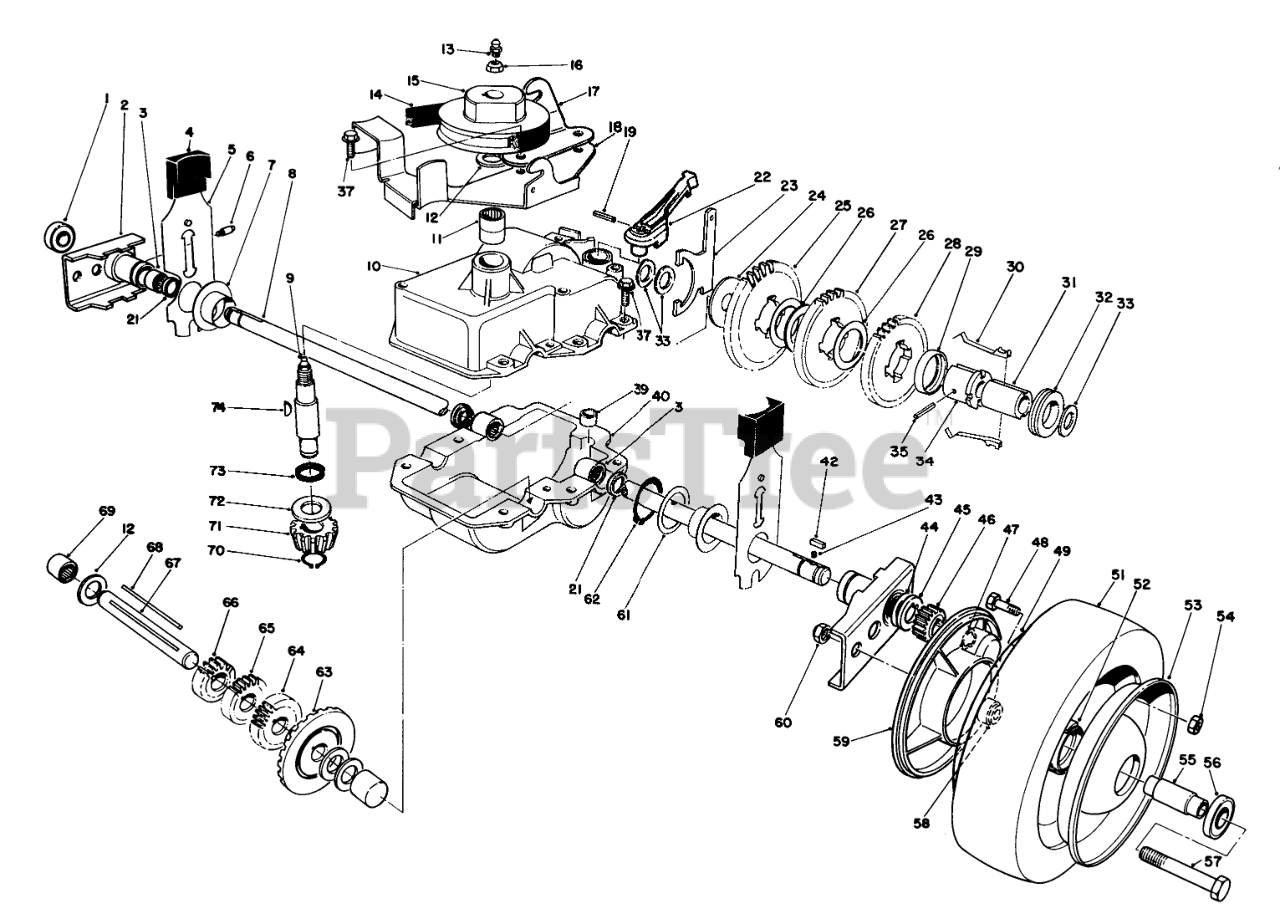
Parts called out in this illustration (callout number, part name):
1	BEARING-WHEEL
2	Pivot Arm Assembly (Incl. Ref. #1, 3, 6 & 21)
3	BEARING-ROLLER
4	KNOB-ARM
5	REAR SPRING ARM ASM
6	FITTING-GREASE
7	CAP-END
8	SHAFT-OUTPUT
9	Shaft-Input (Incl Ref. #13)
10	Upper Case Assembly (Incl. Ref. #11 & 73)
11	BEARING-NEEDLE
12	WASHER-THRUST
13	FITTING-GREASE, ZERK
14	V-BELT
15	PULLEY
16	NUT-HEX
17	Bracket-Traction Engage
18	Belt Guide Bracket
19	PIN-COIL
21	SEAL-OIL
22	LEVER-SHIFT
23	YOKE-SHIFT
24	WASHER
26	WASHER
27	GEAR-42T
28	GEAR-38T
29	RETAINER-KEY
30	KEY-SHIFT
31	SLEEVE
32	COLLAR-SHIFT
33	WASHER-PLAIN
34	SLEEVE-GEAR
35	PIN-GROOVE
37	SCREW-HWHTF
39	BUSHING-YOKE
40	CASE-GEAR, LOWER
42	KEY RECTANGULAR
43	SPRING-COMPRESSION
44	WASHER-THRUST, OUTER
45	WASHER-THRUST, OUTER
46	GEAR-PINION
47	RING-RETAINING
48	SCREW-HH
49	Wheel-Half
52	HUB-BEARING
53	Wheel-Half
54	NUT-LOCK, NI
55	SPACER-BEARING
56	BEARING-WHEEL
57	SCREW-HH
58	SPACER-COVER, WHEEL
59	COVER-WHEEL
60	NUT-LOCK, CONE
61	WASHER
62	RING-RETAINING
63	GEAR-BEVEL
64	GEAR-18T
65	GEAR-14T
66	GEAR-12T
67	SHAFT-INTERMEDIATE
69	BEARING-NEEDLE, CLOSED
70	RING-RETAINING
71	PINION-BEVEL
72	WASHER-THRUST
74	KEY-WOODRUFF
